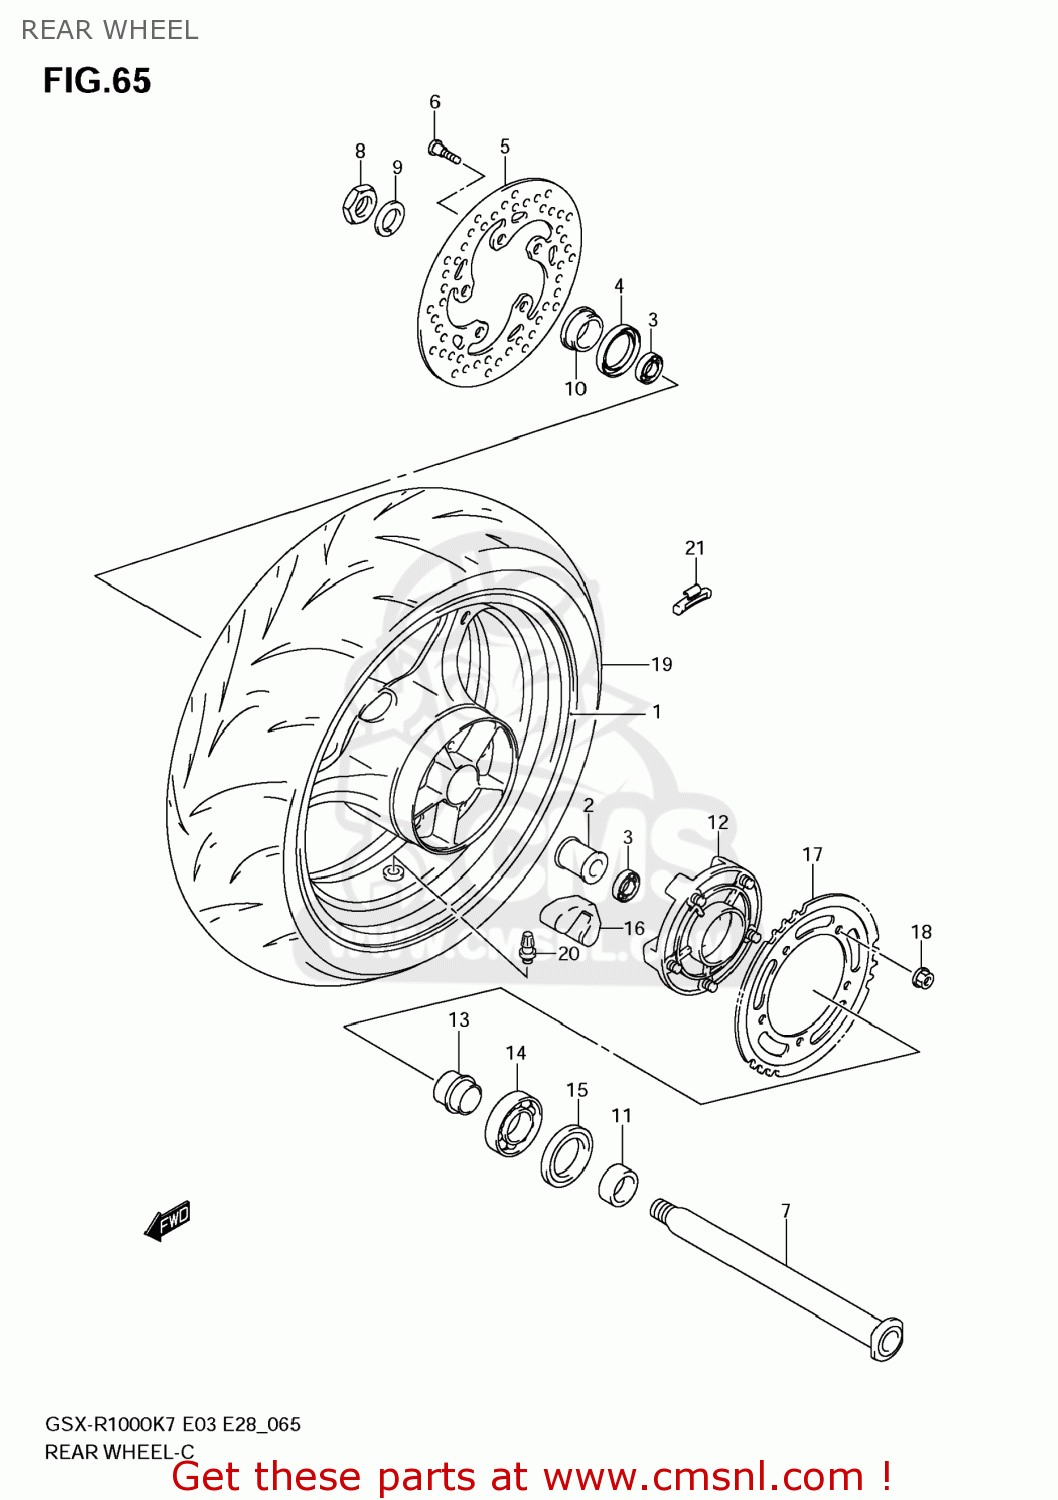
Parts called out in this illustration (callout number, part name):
1	WHEEL,RR(17M/CXMT6.00)
2	SPACER,RR WHEEL BEARING
3	BEARING(28X52X12)
4	SEAL,OIL(37X52X8)
5	DISC,RR BRAKE
6	BOLT(8X21)
7	AXLE,RR
8	NUT
9	WASHER(25.2X42X3.2)
10	SPACER,RR AXLE,R
11	SPACER,RR AXLE,L
12	DRUM,RR SPROCKET
13	RETAINER,RR SPROCKET DRUM
14	BEARING
15	SEAL,OIL(39X65X7)
16	ABSORBER,RR HUB SHOCK
17	SPROCKET,RR(43T-530)
18	NUT
19	TIRE,RR
20	VALVE ASSY,WHEEL RIM(TR412)
21	BALANCER,WHEEL NO.1
